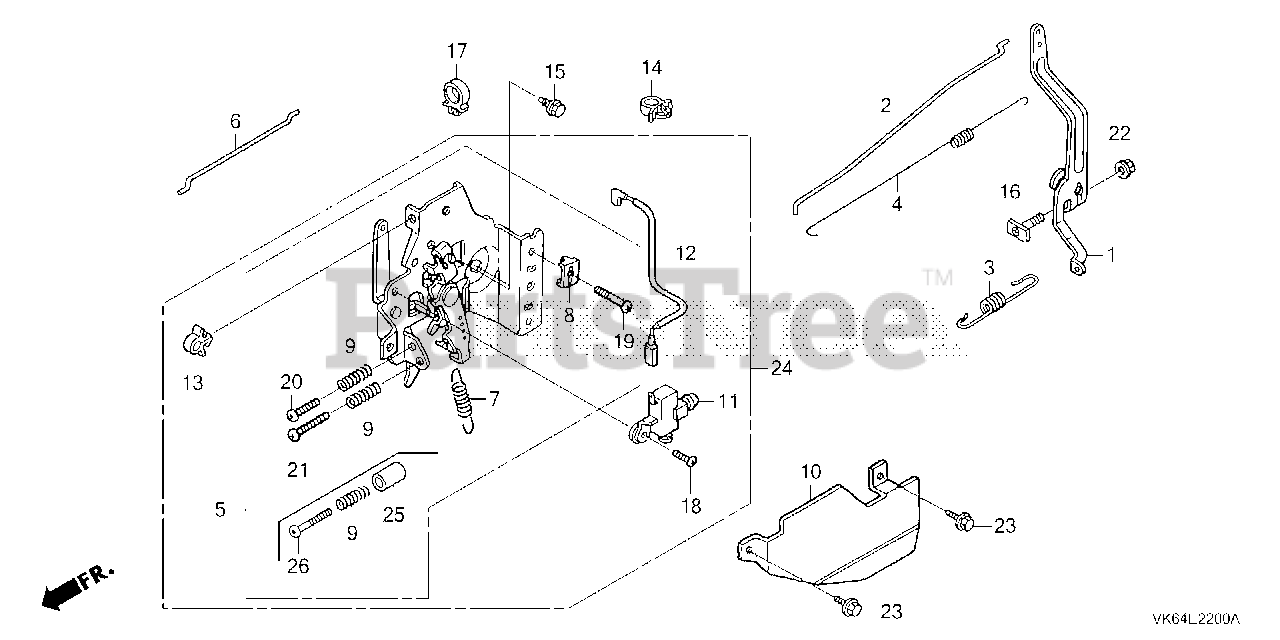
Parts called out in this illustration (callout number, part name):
1	ARM, GOVERNOR
2	ROD, GOVERNOR
3	SPRING, GOVERNOR (STD)
4	SPRING, THROTTLE RETURN
6	ROD, CHOKE
7	SPRING, LEVER
8	HOLDER, CABLE
9	SPRING, CONTROL ADJUSTING Use from Engine SN 2327377.
10	PROTECTOR, CONTROL
15	BOLT, FLANGE (6X12) (CT200)
16	BOLT, GOVERNOR ARM
17	CLIP, HARNESS
19	SCREW, PAN (5X16)
20	SCREW, PAN (5X20)
22	NUT, FLANGE (6MM)
23	BOLT, FLANGE (6X10)
25	COLLAR, STOPPER
26	SCREW, RECESSED (5X28)
